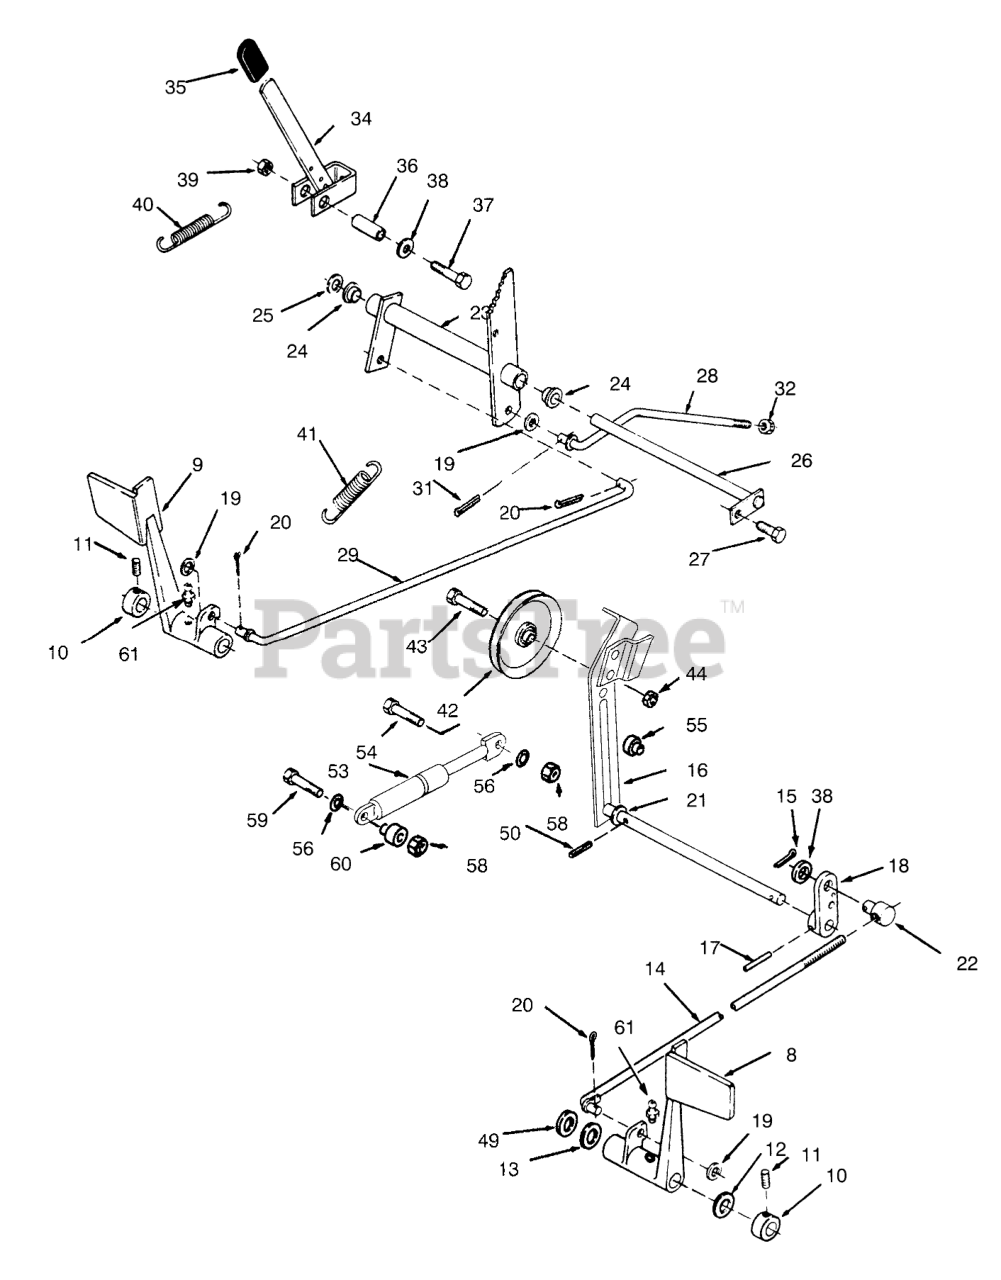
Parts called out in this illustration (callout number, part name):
8	PEDAL-CLUTCH R
9	Pedal-Brake
10	COLLAR
11	SCREW-HSH
12	WASHER-BOWED
13	WASHER
14	ROD AND GUIDE ASM
15	PIN-COTTER
16	Arm-Clutch Idler
17	PIN-SPIROL
18	Arm-Clutch Rod
19	WASHER-NYLON
20	PIN-COTTER
21	SHIM-WASHER
22	TRUNNION
23	Bellcrank Assy
24	BUSHING-FLANGED
25	WASHER-FLAT
26	ROD ASM
27	SCREW
28	ROD-REAR BRAKE
31	Hairpin Cotter
32	NUT-LOCK, NI
34	ASSY-BRAKE LEVER WAB
35	GRIP
36	SPACER
37	SCREW-HH
38	WASHER-FLAT
39	LOCKNUT-FLANGE
40	SPRING-BRAKE
41	SPRING-EXTENSION
42	PULLEY-IDLER
43	BOLT-SPECIAL HEX
44	NUT-HEX
49	Washer
50	PIN-SPIROL
53	ASS'Y-GAS SPRING
54	Capscrew
55	SPACER-SHOULDER-.200
56	WASHER-FLAT
58	NUT-LOCK, NI
59	SCREW-HH
60	SPACER-SHOULDER-.400
61	FITTING-GREASE
